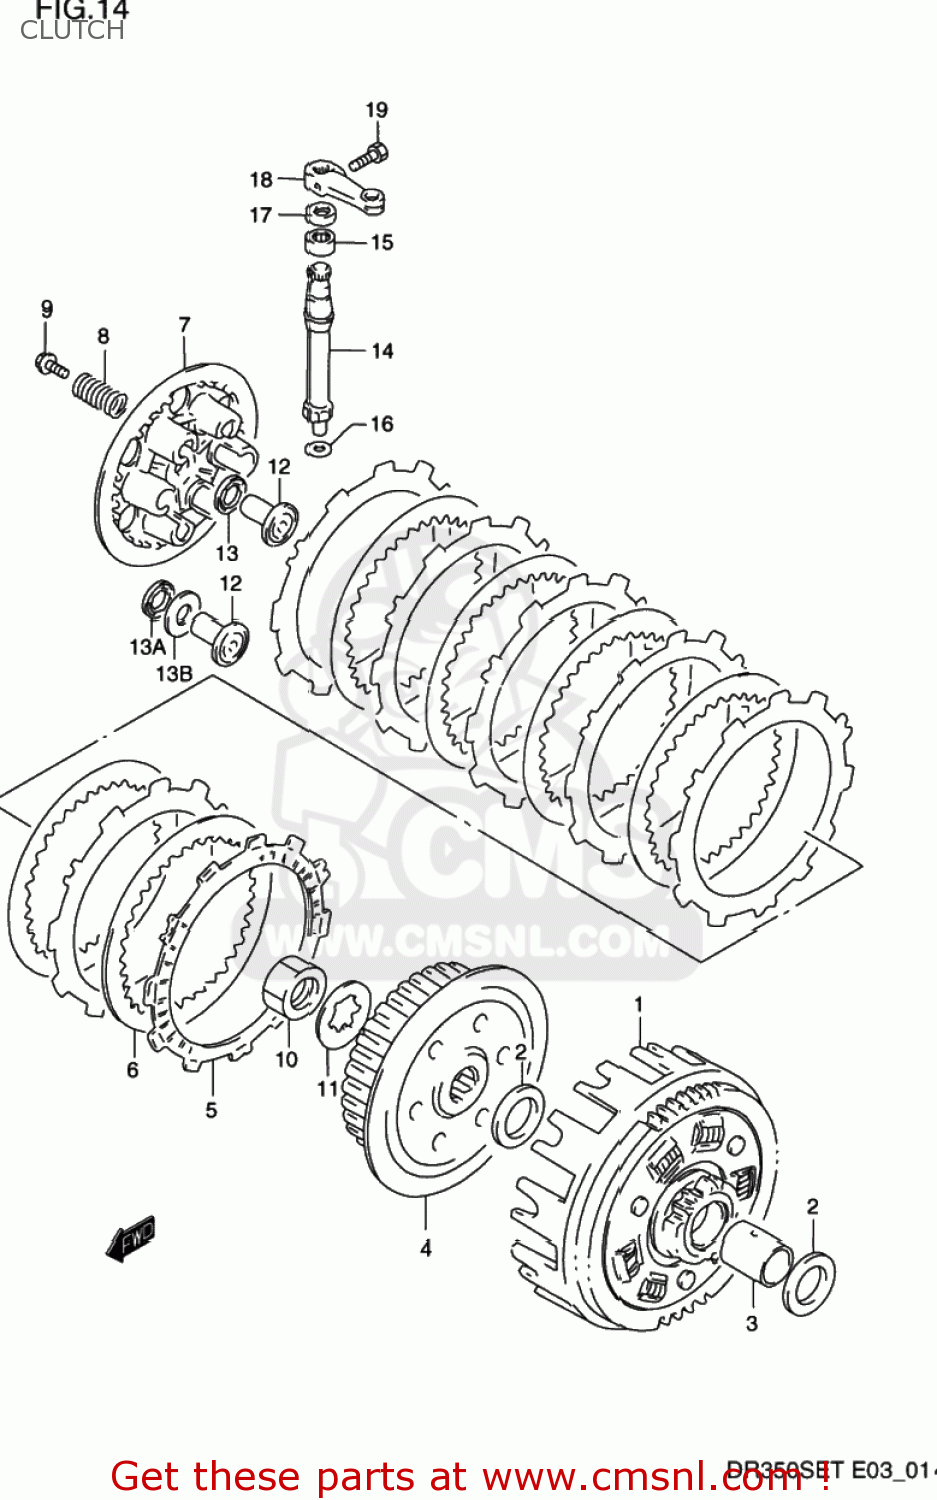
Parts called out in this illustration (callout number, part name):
1	GEAR ASSY,PRI DRIVEN(62/15
2	WASHER
3	SPACER(20X25X29)
4	HUB,CLUTCH SLEEVE
5	PLATE,CLUTCH DRIVE (NAS)
6	PLATE,CLUTCH DRIVEN (NAS)
7	DISC,CLUTCH PRESSURE
8	SPRING
9	BOLT 5X16
10	NUT (20MM)
11	WASHER,LOCK
12	RACK,CLUTCH RELEASE
13	BEARING(10X22X2.8)
13A	BEARING(10X24X2)
13B	WASHER
14	PINION,CLUTCH RELEASE
15	BEARING(12X16X10)
16	WASHER
17	SEAL,OIL(10X17X5)
18	ARM,CLUTCH RELEASE
19	BOLT
